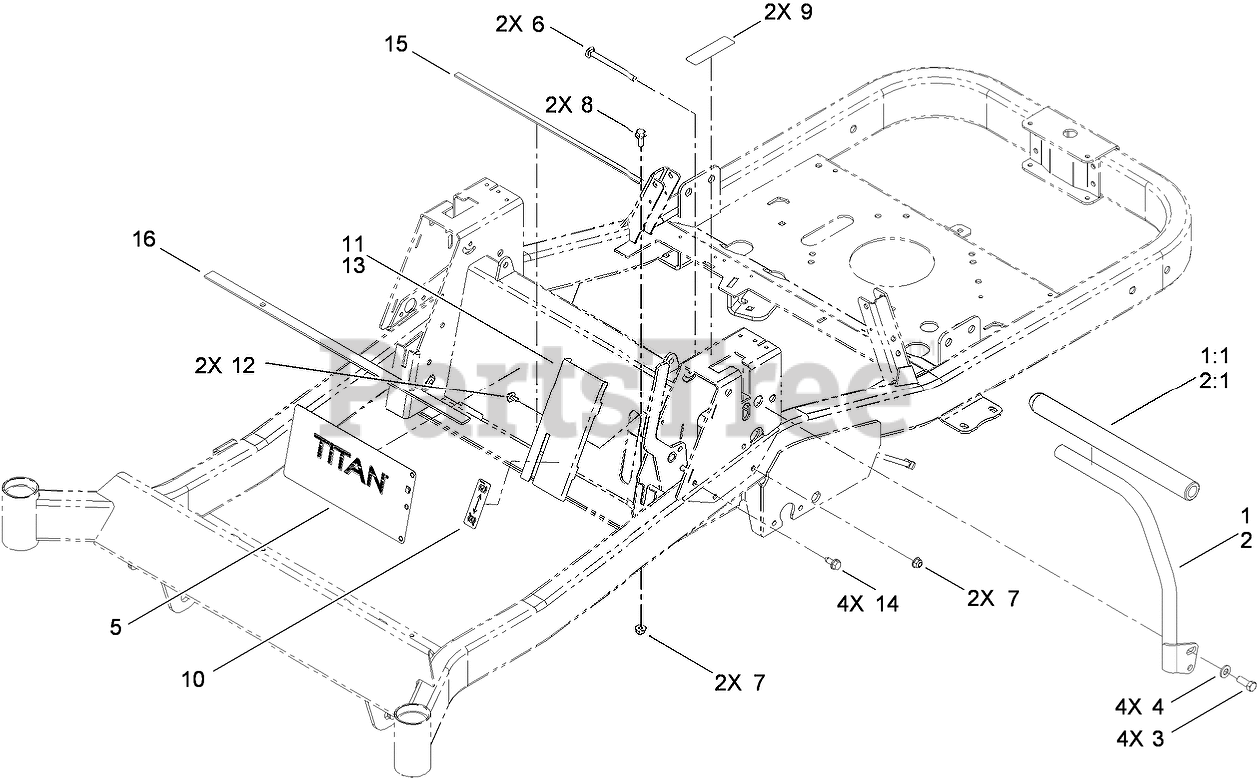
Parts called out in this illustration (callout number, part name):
1	LH CONTROL HANDLE ASM
3	SCREW-HH
4	WASHER-FLAT
5	DECAL-TITAN
6	SCREW-CARR
7	NUT-HF, NI
8	SCREW-HHF
9	DECAL-CONTROL, MOTION
10	DECAL-BRAKE, PARKING
11	COVER-CONTROL, LH
12	SCREW-HHFTF
14	SCREW-HWHTF
15	STRIP-VIBRATION, ANTI
16	STRIP-VIBRATION, ANTI
